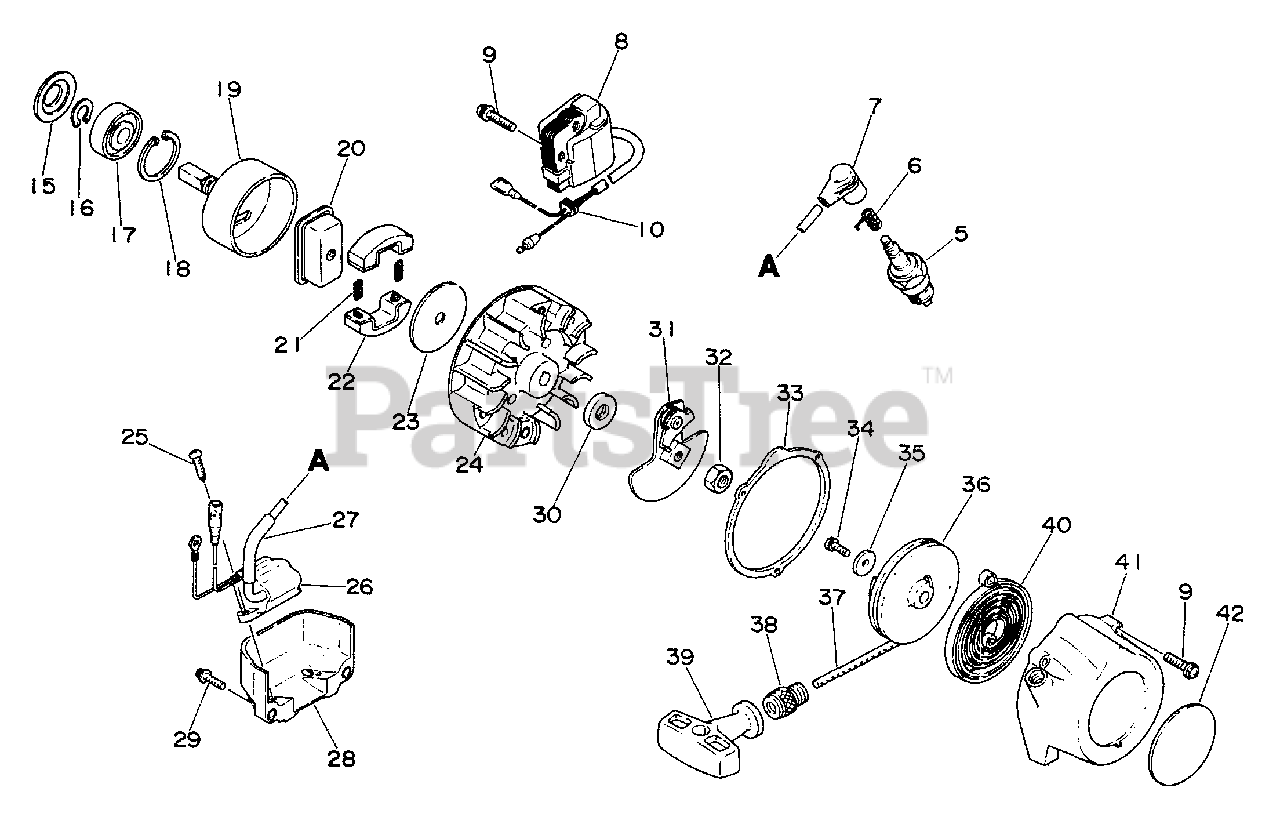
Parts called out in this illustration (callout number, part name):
5	SPARK PLUG - CJ8
6	TERMINAL, SPARK PLUG
7	CAP, SPARK PLUG
8	COIL, IGNITION
9	SCREW 4×20
15	STOPPER, PIPE
16	RING, RETAINING - 12
17	BEARING, BALL
18	RING, SNAP Ø32
19	DRUM, CLUTCH
20	BOSS, CLUTCH
21	SPRING, CLUTCH
22	SHOE, CLUTCH
23	PLATE, CLUTCH
24	FLYWHEEL
25	SCREW - 4×16 -- TAPPING
26	COIL, IGNITION
27	PIPE
28	CASE
29	SCREW 4×14
31	PAWL ASSY, STARTER
32	NUT 8×1.25
33	GASKET, STARTER
34	SCREW - 4×10
35	WASHER 4.1×15.5×1T
36	REEL, ROPE
37	ROPE, STARTER 3.0×850
38	GUIDE, ROPE
39	GRIP, STARTER
40	SPRING, RECOIL
41	CASE, STARTER
42	LABEL, ECHO
